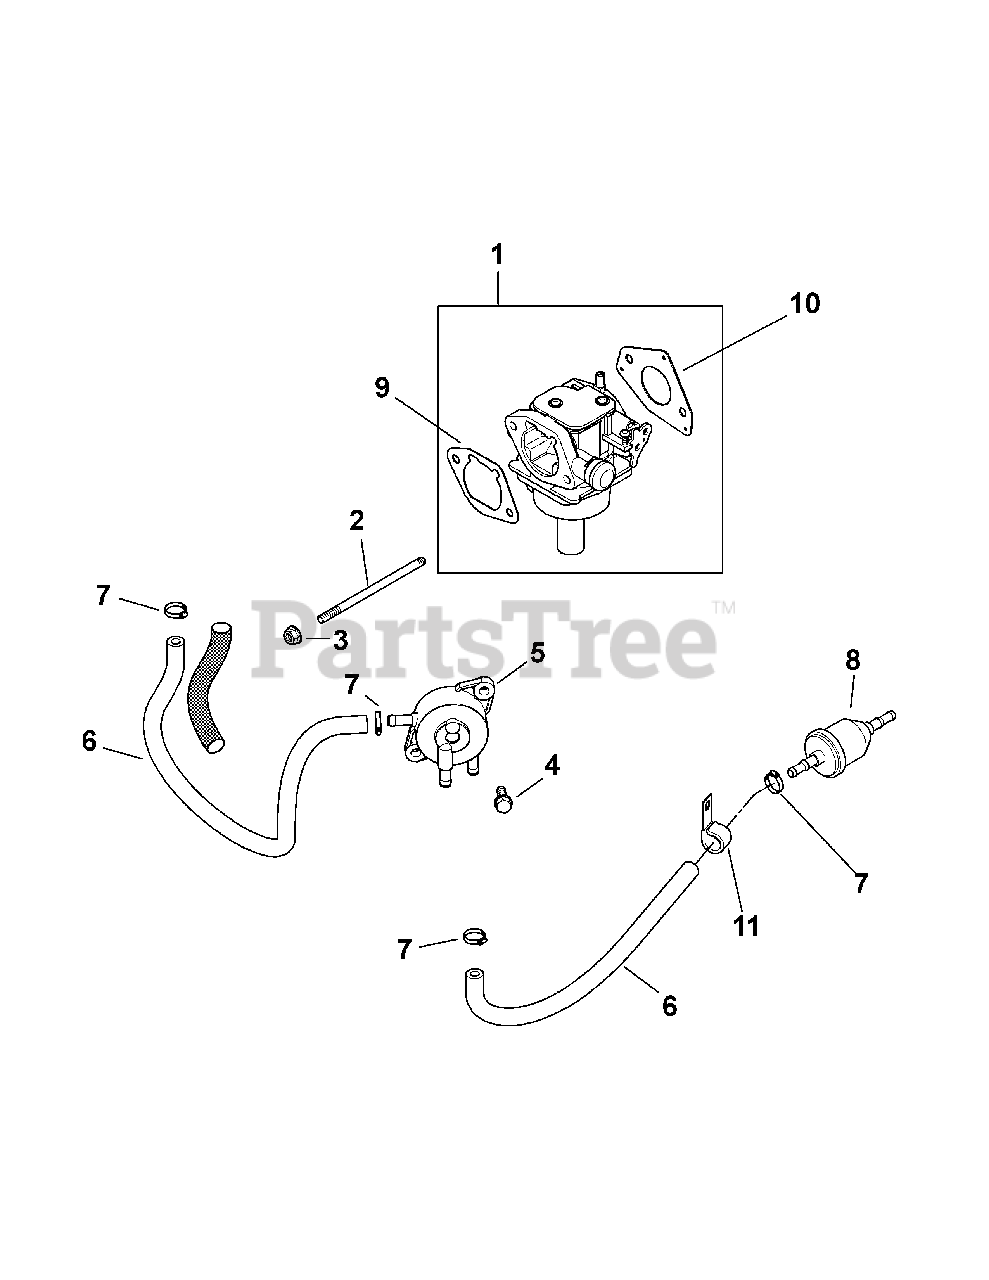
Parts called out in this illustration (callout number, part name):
1	Carburetor Kit
2	Stud, M6 x 1.0 x 106
3	Flange Nut, M6 x 1.0
4	Tap Screw, M6 x 1.7 x 18
6	Fuel Line
7	Hose Clamp, 1/2
9	Air Cleaner Base Gasket
10	Carburetor Gasket
